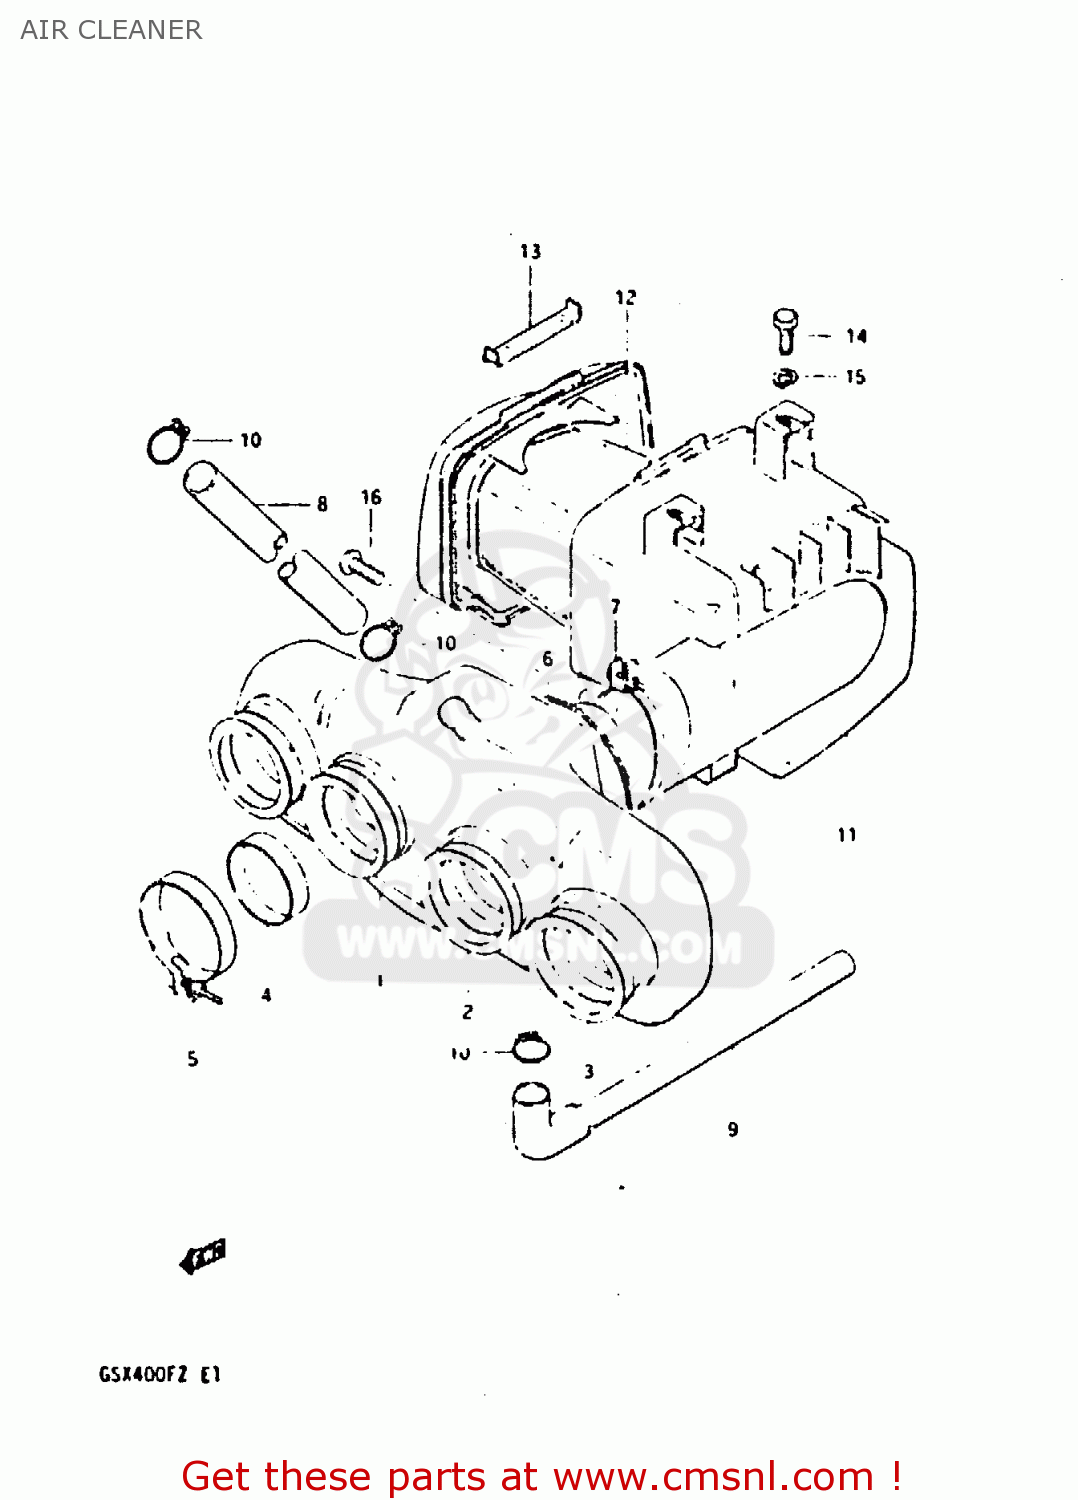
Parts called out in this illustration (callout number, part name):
1	CASE ASSY, FRONT
2	TUBE,INNER
3	TUBE, OUTLET OUTER
4	RING,CARBURETOR AIR IN
5	CLAMP
6	JOINT,HOSE AIR CLEANER
7	CLAMP
8	TUBE,BREATHER
9	DRAIN TUBE
10	CLIP
11	CASE SET, REAR
12	FILTER ASSY
13	SLIDER
14	BOLT, UPPER
15	LOCK WASHER
16	SCREW
